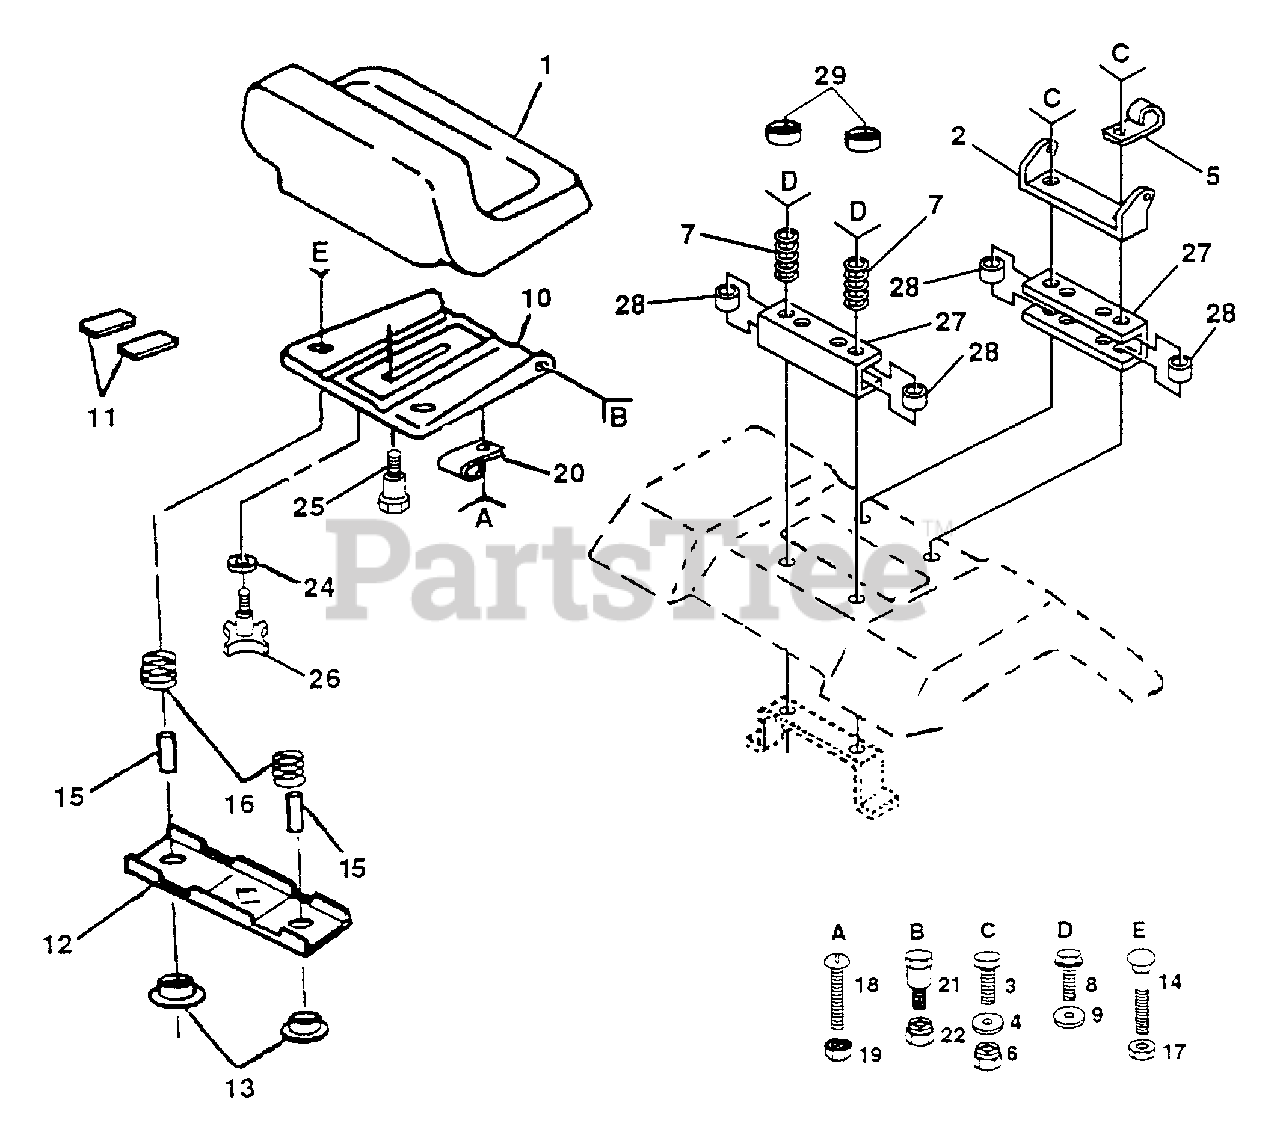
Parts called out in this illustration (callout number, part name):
1	Seat
2	Bracket Pivot Seat
3	Bolt, Hex 3/8-16unc X 2-1/2
4	Washer 13/32 X 1 X 10 Ga
5	Clip Fuel Line
6	Nut, Crownlock 3/8-16 Unc
7	Spring Seat Cprsn
8	Screw Hwsh Thdrol 3/8-16x2-1/2
9	Washer 13/32 X 1 X 14 Ga
10	Pan Seat
11	Strip Foam
12	Bracket Mounting Switch
13	Bushing Snap
14	Bolt 1/4-20x1-3/8
15	Spacer Split
16	Spring Cprsn
17	Locknut 1/4 Gr. 5
18	Screw SLTD Pan Hd #10-32 X 1/2
19	Nut, Keps #10-32 Unf
20	Clip Insulated
21	Bolt, Shoulder 5/16-18 Unc
22	Nut, Crownlock 5/16-18
24	Washer 17/32 X 1-3/16 X 12 Ga
25	Bolt, Shoulder 5/16-18 X 62
26	Knob Seat 1/2-13unc
27	Spacer, Seat
28	Spacer Split
29	Cap Spring Seat
